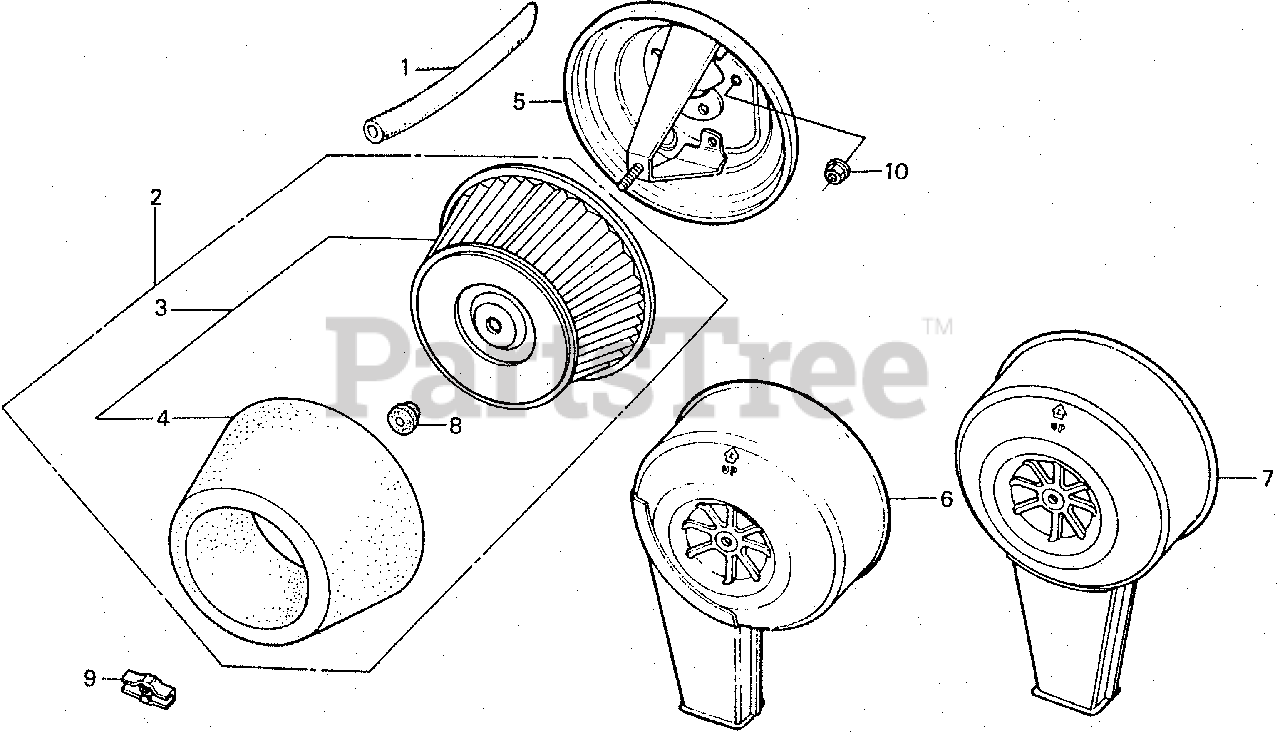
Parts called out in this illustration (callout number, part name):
1	TUBE, BREATHER
3	ELEMENT, AIR CLEANER
5	HOUSING, AIR CLEANER
5	HOUSING, AIR CLEANER (NOT AVAILABLE)
6	COVER, AIR CLEANER
7	COVER, AIR CLEANER
8	GROMMET, AIR CLEANER
9	WINGNUT, AIR CLEANER COVER
10	NUT, FLANGE (6MM)
